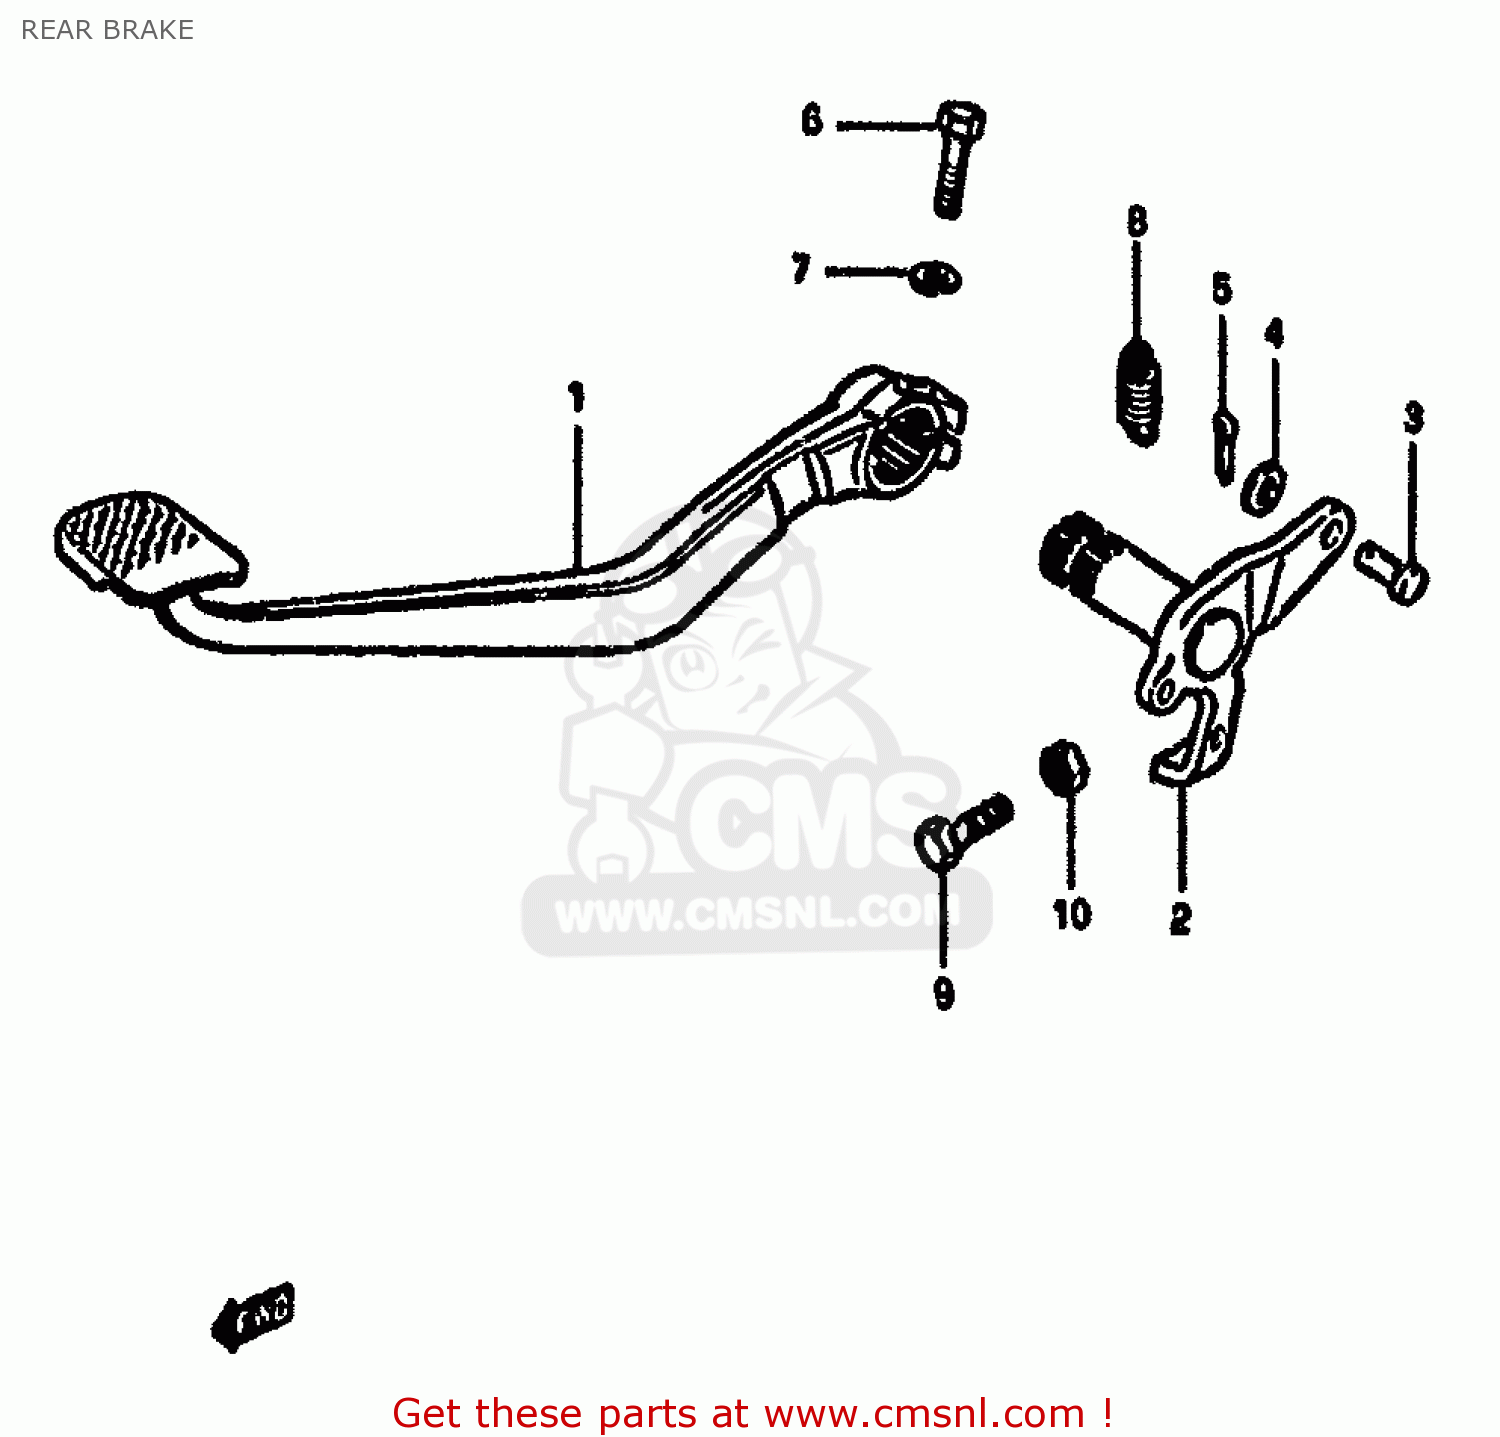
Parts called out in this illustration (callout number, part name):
1	PEDAL, BRAKE
2	ARM,BRAKE PEDAL
3	PIN
4	WASHER
5	PIN
6	BOLT
7	LOCK WASHER
8	SPRING
9	BOLT
10	NUT
